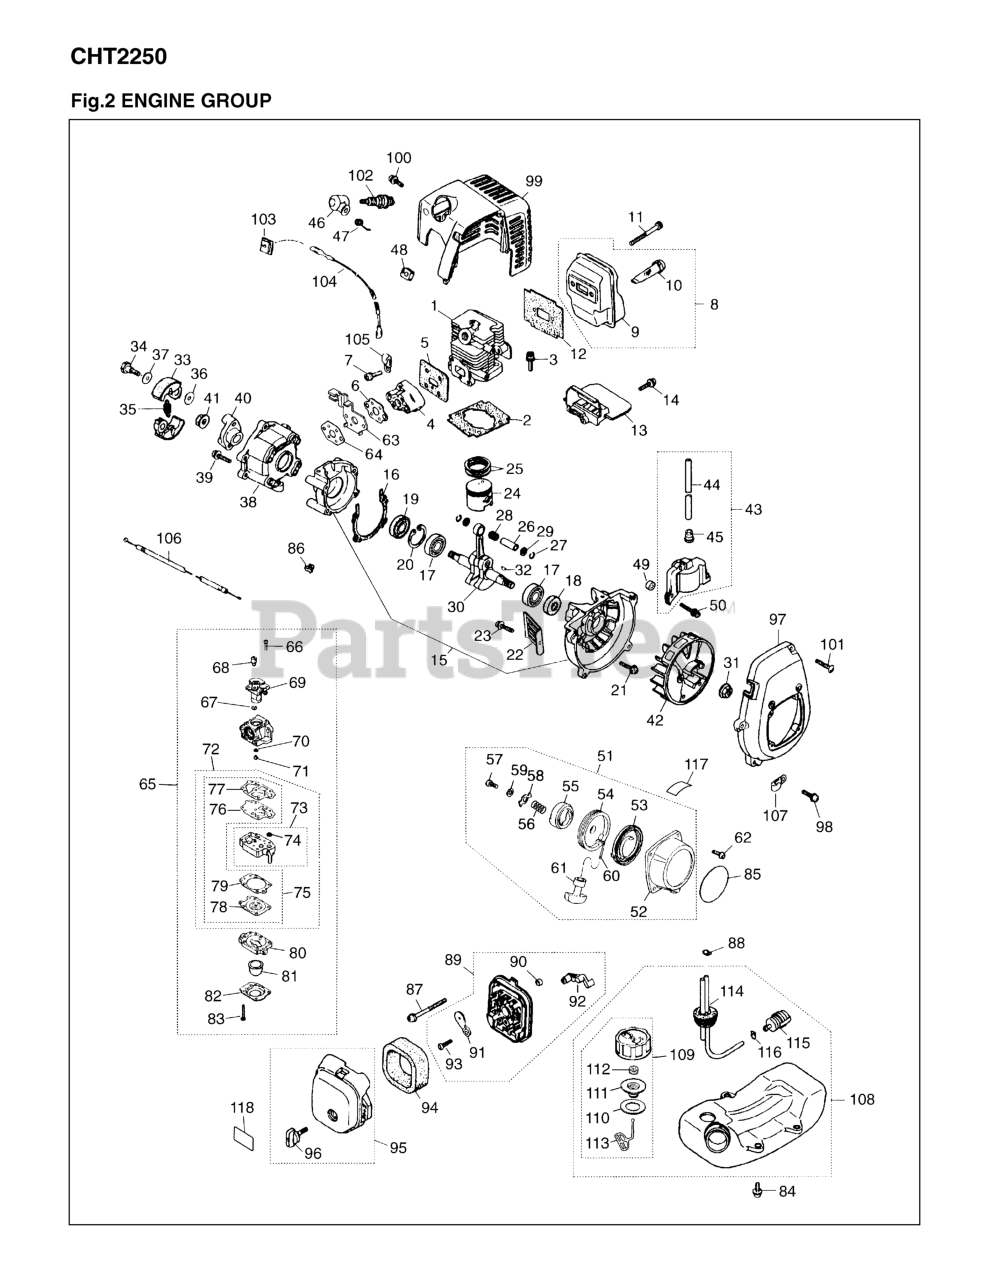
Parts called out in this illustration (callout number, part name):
1	CYLINDER
2	GASKET, BASE (RPLS -12212)
3	BOLT, M5 X 22
4	INSULATOR (REPLACES -13162)
5	GASKET (RPLS 550013121/13120)
6	GASKET (REPLACES -13130)
8	MUFFLER ASSEMBLY
10	ARRESTER (RPLS 5850-15140)
11	BOLT, M5 x 50
12	GASKET, MUFFLER
14	SCREW, M4 X 16
15	CRANKCASE COMP.
16	GASKET (RPLS -21140)
17	BEARING
18	SEAL, OIL (RPLS 1100-21210)
19	SEAL
20	RING
21	BOLT, M5 X 30
23	SCREW
24	PISTON (REPLACES 1140-41110)
25	RING, PISTON (RPLS 1850-41210)
26	PIN, PISTON 5x8x26
27	RING
28	BEARING
29	WASHER
30	CRANKSHAFT (RPLS -42000)
31	NUT
32	KEY
33	SHOE (RPLS 1100-51114)
34	SCREW
35	SPRING
36	WASHER
37	WASHER
38	CASE, CLUTCH
39	SCREW
40	PLATE, CLUTCH
41	NUT
43	COIL
45	CAP
46	CAP
47	SPRING
48	GROMMET
49	SPACER
50	BOLT
51	RECOIL-ASSY (RPLS -75101)
52	CASE, RECOIL
53	SPRING
54	REEL (RPLS-75130 & 1861-75130)
55	RACHET (RPLS.-75140)
56	SPRING (REPLACES -75150)
58	RETAINER
59	WASHER
60	ROPE
61	KNOB (REPLACES-75180)
62	SCREW, M4 x 12
63	BRACKET
64	GASKET (REPLACES -13130)
65	CARBURETOR
67	RING
68	SWIVEL
69	VALVE
70	O-RING
73	BODY ASSY
74	SCREEN
76	DIAPHRAGM, PUMP
77	GASKET, PUMP
78	DIAPHRAGM
79	GASKET, DIAPHRAGM
80	BODY, PURGE
81	PUMP, PRIMING
82	COVER, PUMP
83	SCREW
84	SCREW
85	LABEL, RECOIL
86	CAP, CABLE END
87	SCREW, M5 x 60
88	CLIP
89	BODY-A (RPLS -82101)
90	SLEEVE
91	PLATE, CHOKE (RPLS-82130)
92	LEVER
93	SCREW
94	ELEMENT
95	COVER ASSY (RPLS -82202)
96	KNOB
97	COVER, FAN
99	ENGINE COVER (RPLS-32100)
100	SCREW, M5 x 12
101	SCREW, HOUSING
102	PLUG, SPARK (RPLS 5602-73110)
104	CORD
105	CLAMP
106	CABLE
107	CLAMP
108	TANK ASSY
109	CAP ASSY (RPLS. 5601-85201)
110	PACKING
111	HOLDER - A (RPLS 5601-85230)
112	FILTER
113	STOPPER
114	PIPE COMPLETE
115	FILTER (RPLS 1850-85300)
116	CLIP
117	LABEL
118	LABEL, CAUTION
